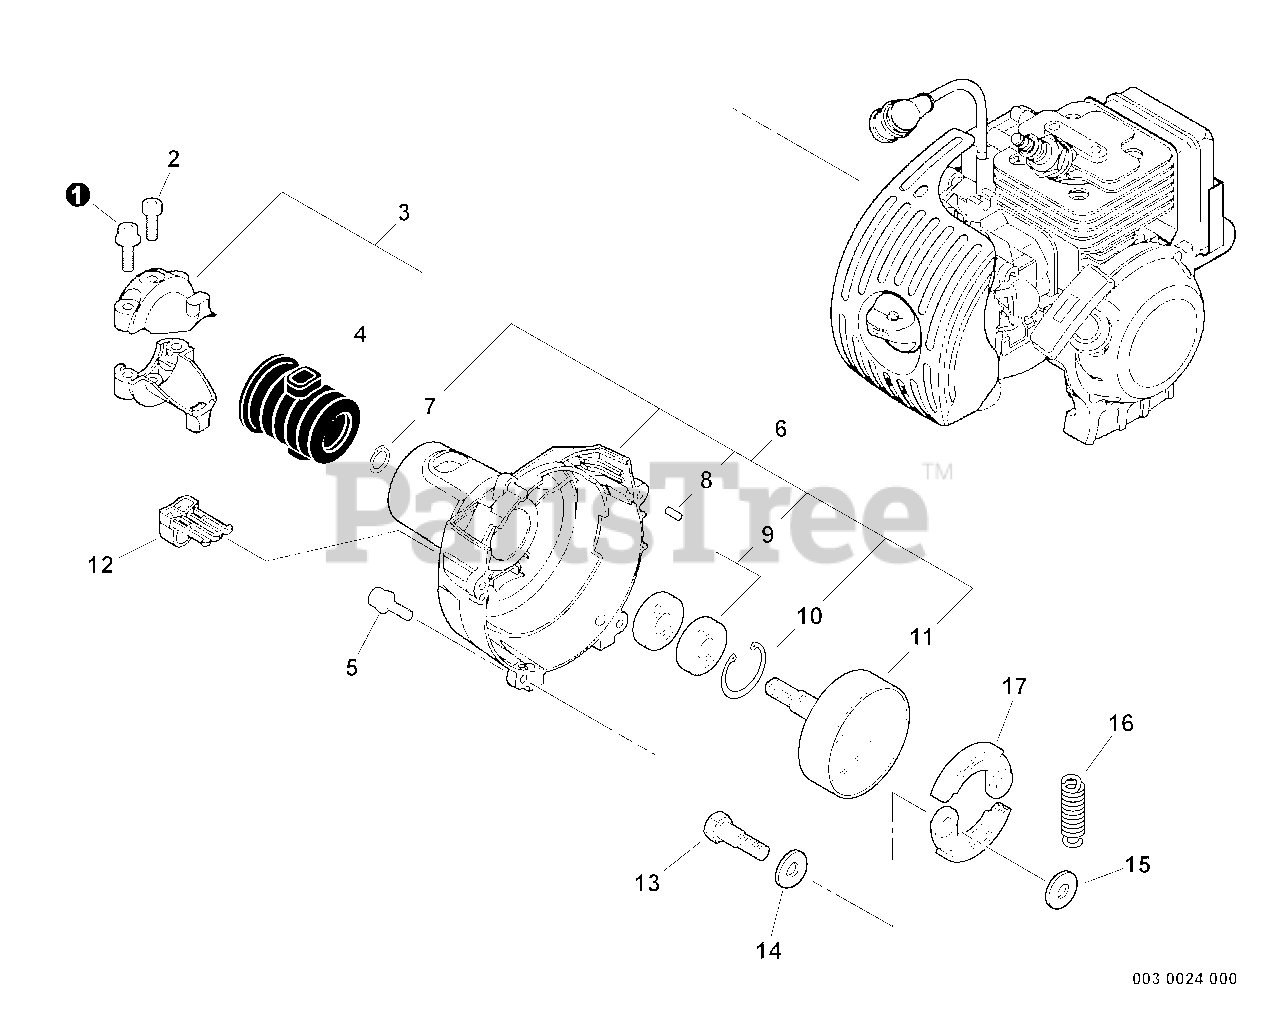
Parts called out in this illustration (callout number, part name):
1	SCREW - 5X25
2	SCREW - 5X12
3	MAIN PIPE CLAMP KIT
4	CUSHION
5	SCREW - 4X16
6	FAN CASE ASSY
7	RING, RETAINING - 12
8	PIN - LOCATING
9	BEARING, BALL - 6001
10	RING, RETAINING - 28
11	DRUM, CLUTCH
13	BOLT, CLUTCH
14	WASHER - SPRING
15	WASHER - 6
16	SPRING, CLUTCH
17	SHOE, CLUTCH
